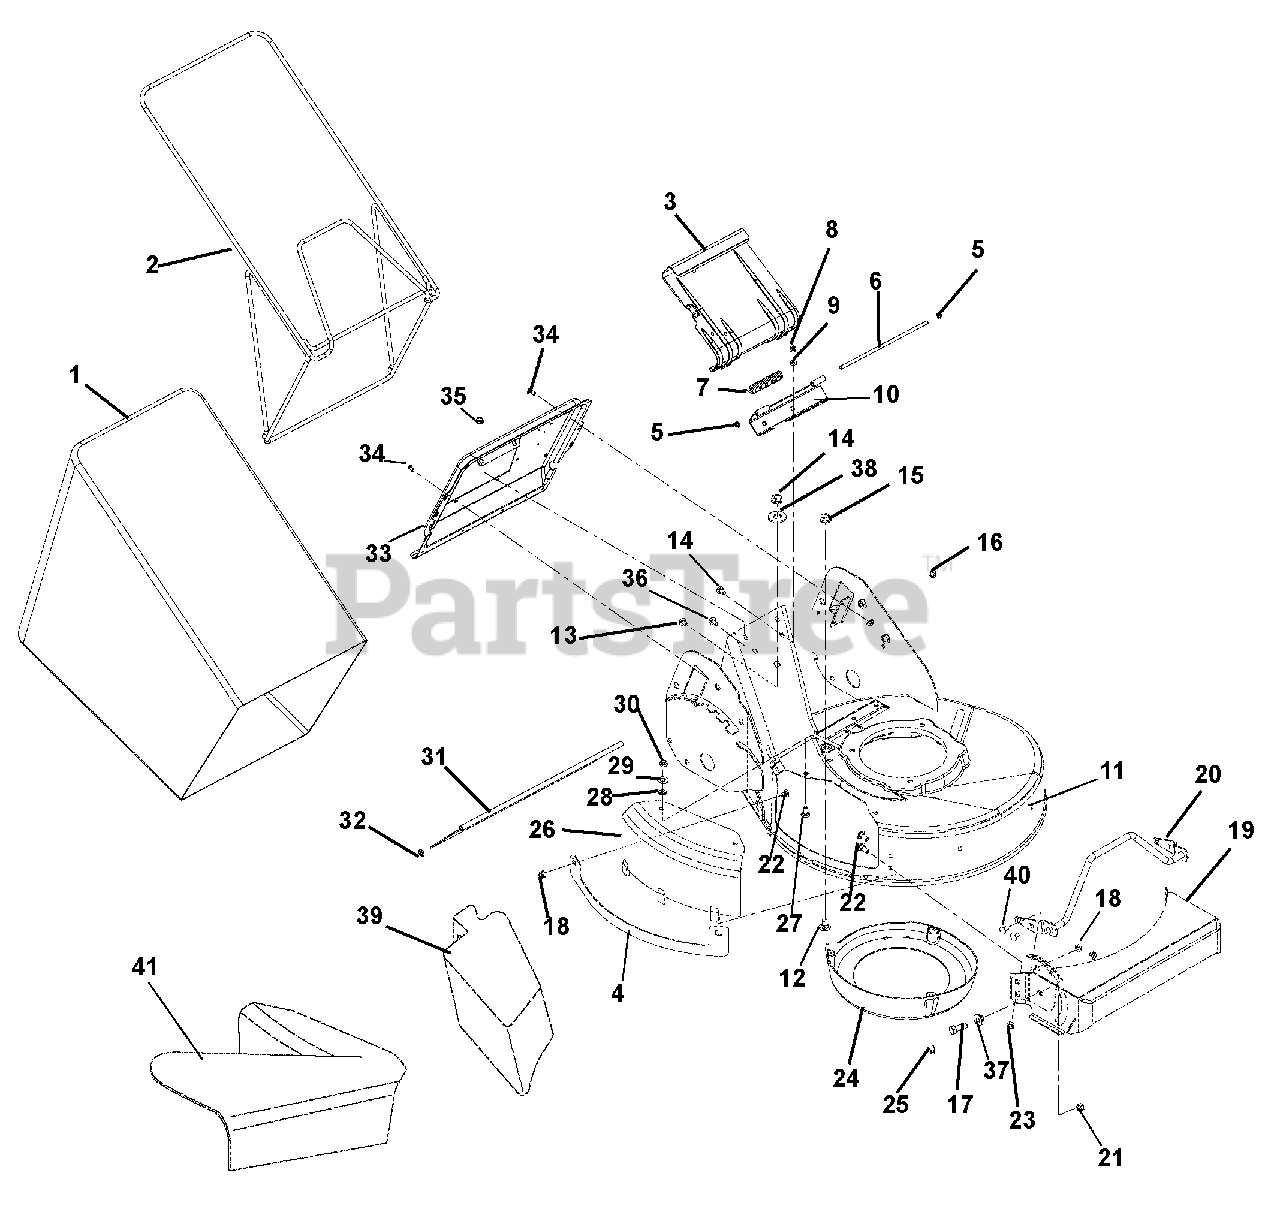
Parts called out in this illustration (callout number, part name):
1	Bag, Consumer Black 15 OZ/YD2
2	Frame, WBLM Bagger
3	Catcher Plate Door
4	Bracket, Discharge Guard
5	Push Nut, .25
6	Door Pin
7	Spring, Torsion .120 x .68 x 3.09
8	Nut, Hex .25-20
9	Washer, Locking .250 x .077 Heavy
11	Kit, XD21 Deck with Decals
12	Bolt-Hex .25-20X.50 Grade 5
13	Bolt-Hex .38-16X.50 Grade 5
14	Bolt, Round Head Square Neck .25-20 x .75 Grade 5
15	Nut-Locking-Flange .25-20
16	Plastic Grommet
17	Bolt, Hex .31-18 x 1.00 Grade 5
18	Nut, Locking-Top-Flange .31-18
19	Weldment, Commercial 21 Bumper
20	Angle, Support
21	Nut, Locking-Center .31-18
22	Bolt, Round Head Square Neck .31-18 x .75 Grade 5
23	Nut, Spin Lock-Flange .312-18
24	Center Baffle
25	Screw, Tapping 10-16 x .62 SLPH AB
26	Cover, Side Discharge
27	Bolt, Round Head Square Neck .31-18 x .75 Grade 2
28	Nut-Push .312
29	Washer, Flat-Steel .406 x .812 x .065
30	Nut, Locking-Nylon .312-18
31	Trailing Shield
32	Retainer, .38 Push-On
33	Catcher Plate
34	Screw, Tapping 1/4-20 x 3/4 LPAN
35	Nut, Locking-Flange .250-20
36	Bolt, Round Head Square Neck .25-20 x .50 Grade 5
37	Bushing, Flange .32 x .500 x .344 x .880
38	Washer, Flat-Steel .511 x 1.441 x .125
39	Plug, Mulchmaster Mulcher
40	Bolt, Round Head Square Neck .31-18 x .62 Grade 5
41	Side Discharge Assembly
